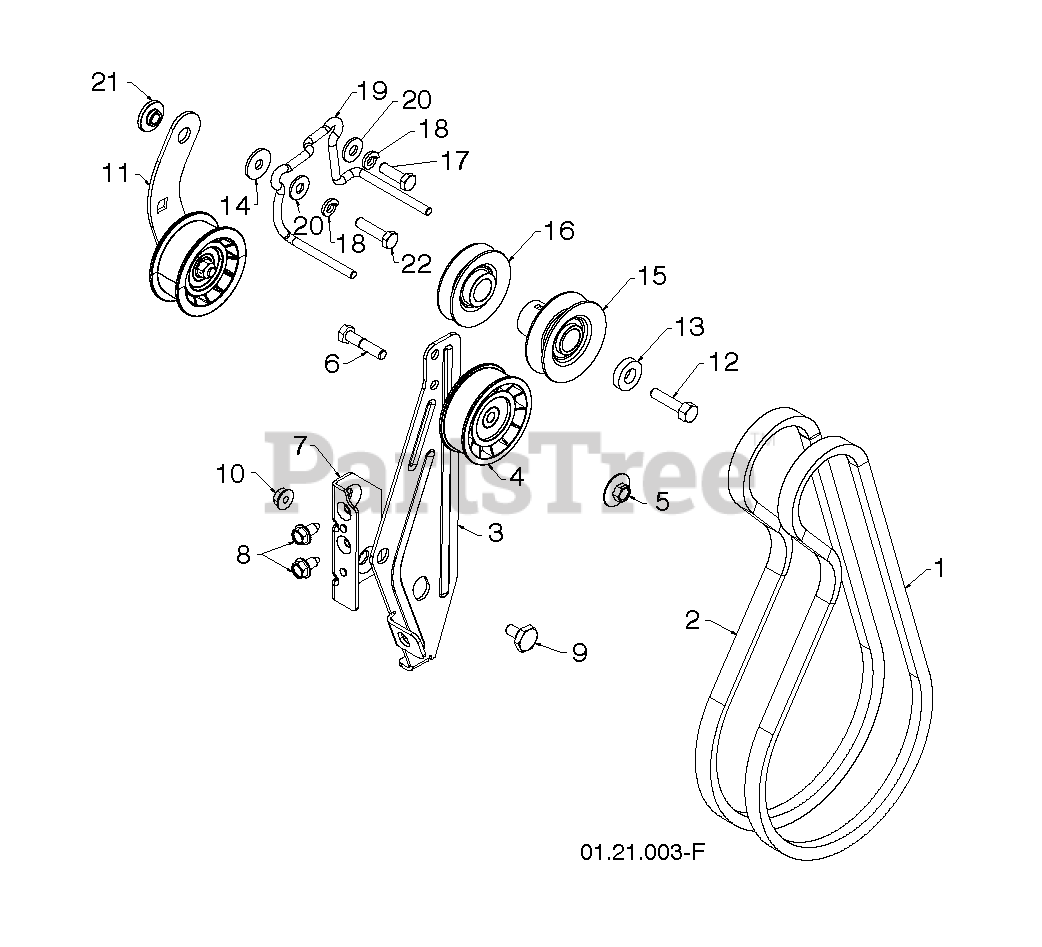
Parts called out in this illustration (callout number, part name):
1	BELT.V.IMPELLER
2	V-BELT TRACTION 34.25
3	ARM.IDLER BRAKE.CLEAR.ZINC
4	PULLEY.W/SPACER.2.75
5	NUT.FLANGE.HEX.5/16X18.BLACK
6	HEX BOLT
7	RP.BRACKET.IDLER.PIVOT.BLACK
8	BOLT.5/16HEX.WHS.HD
9	BOLT.SHOULDER.1/2X12
10	NUT.LOCK.5/16-18
11	ARM.ASM.TRACTION.IDLER.
12	SCREW, HEX HD 3/8-24 X 1-3/8
13	WASHER, FLAT 3/8
14	STEEL WASHER
15	PULLEY.ENG.TRACTION
16	PULLEY.ENG.TRACTION
18	WASHER.LOCK.HVY.HLCL.SPR.5/16
19	RB GUIDE.BELT.CHAIN.LS.SNOW
20	WASHER.20X8.5
21	RP BUSHING, IDLER PIVOT
22	CAPSCREW.HEXHD.5/16X1.25.
